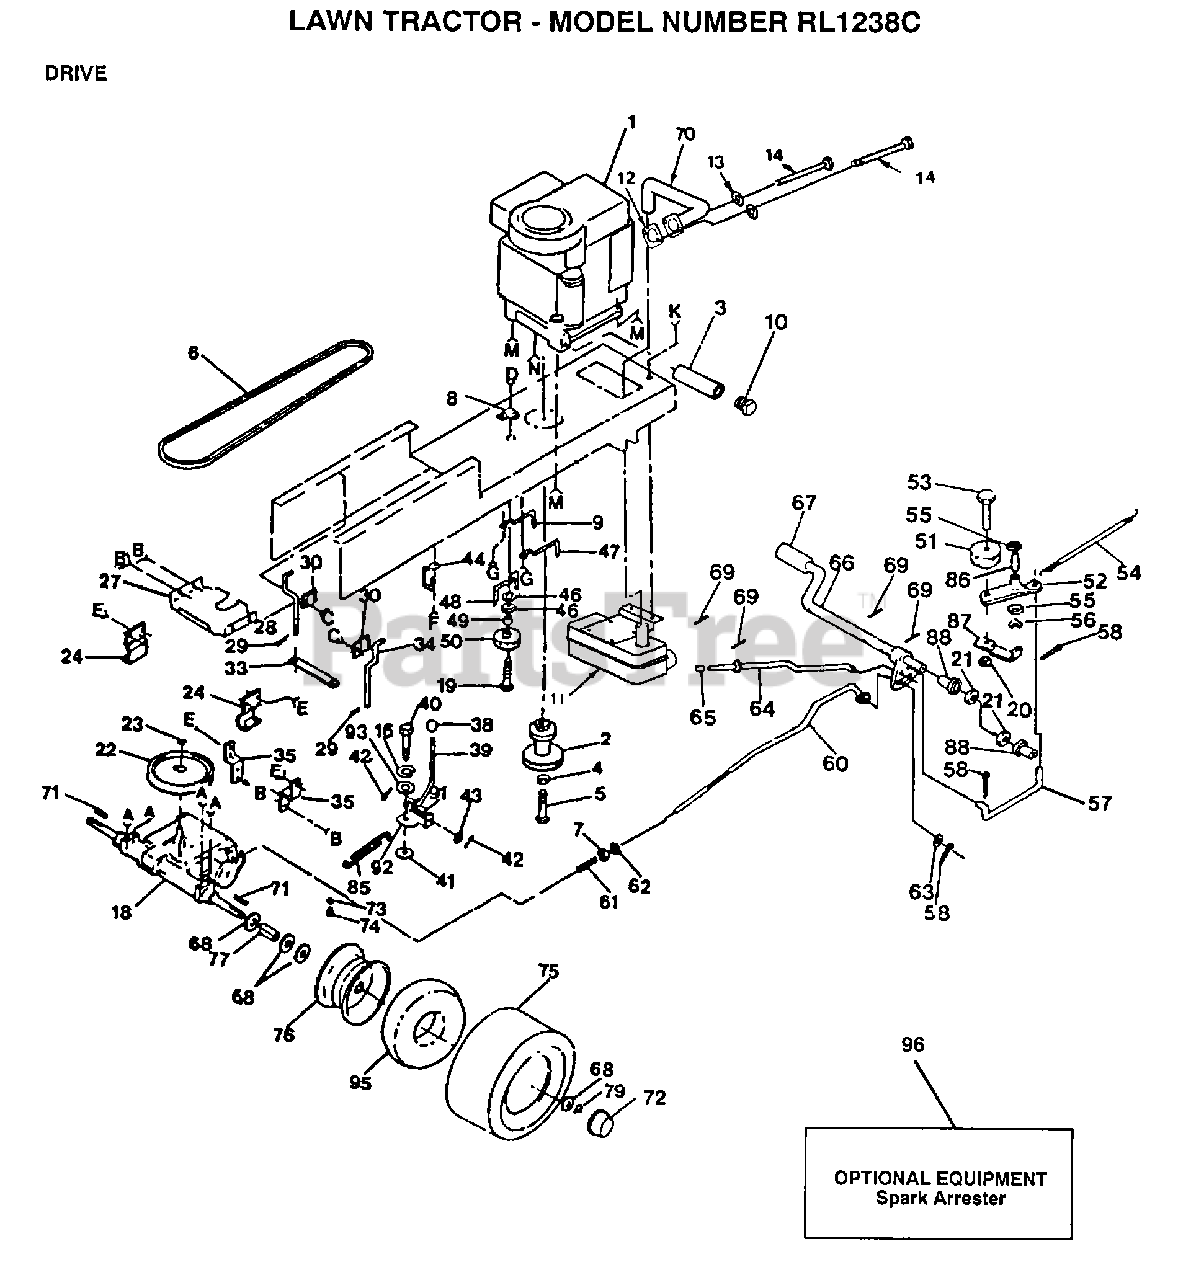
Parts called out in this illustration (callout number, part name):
1	ENGINE BRIGGS AND STRATTON
4	LOCKWASHER
5	BOLT
6	BELT-V.90.0.GD.DR
7	NUT
8	CLIP T
9	KEEPER BELT ENGLH
11	MUFFLER EUROPE
13	LOCKWASHER
14	SCREW LT
15	SCREW
16	LOCKWASHER
19	BOLT
21	WASHER LT
22	PULLEY TRANS
24	BRACKET LT
25	BOLT
26	SCREW
27	BRKT SUPPORT LT
28	KEEPER BELT LH
29	SPRING.RETAINER
30	CLAMP LT
31	BOLT
33	STRAP LOCATOR
34	KEEPER BELTRH
35	STRAP TORQUE
38	CONTROL KNOB LT
39	ROD SHIFTER
41	WASH-SHFT PLT LT
42	PIN COTTER 1/8
43	WASHER
45	SCREW
46	WASHER
47	"KEEPER,BLT ENG LT"
48	BELT KEEPER LT
49	SPACER T
50	PULLEY.IDLER.FLAT
52	ARM IDLER
54	"SPRING, RETURN LT"
55	WASHER LT
56	KLIP RING
57	"LINK, CLUTCH T"
58	COTTER PIN
60	BRAKE ROD LT
61	SPRING ROD LT
62	NUT
63	WASHER
67	PEDAL COVER T
68	WASHER
70	PIPE EXHAUST
71	SQUARE KEY
72	HUB CAP
73	VALVE CAP
74	VALVE STEM LT
75	TIRE.TS2.18X8.5
77	SPACER LT
79	E-RING LT
83	WASHER
86	"LY, BEARING"
87	RETAIN BELT
88	NYLON BEARING
91	SPRING LT
92	PLATE SHIFT LT
93	WASHER LT
94	LOCKWASHER
95	TUBE.18X9.5-8
96	SPARK ARREST KIT
